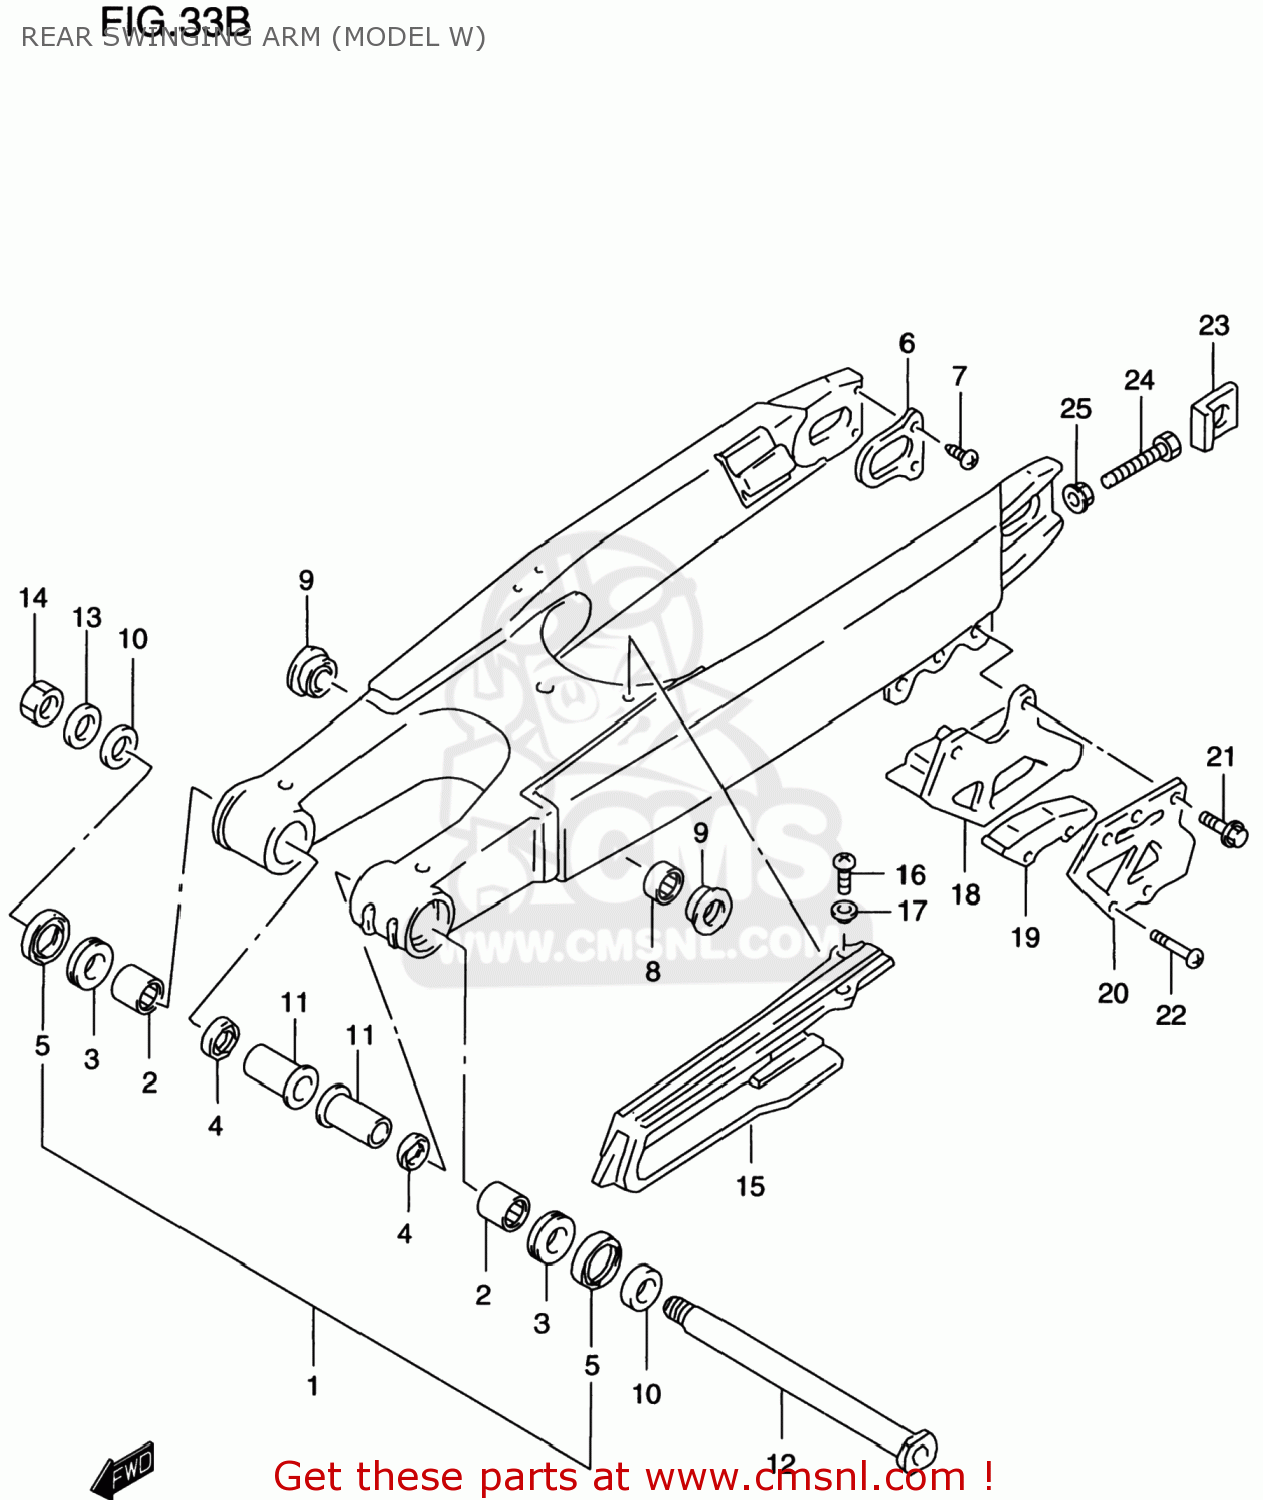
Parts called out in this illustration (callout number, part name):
1	SWING ARM ASSEMBLY,REAR
2	BEARING(22X29X30)
3	BEARING(22X35X2)
4	SEAL,OIL(22X29X4)
5	SEAL,RR SWGARM PIVOT OUTER
6	PLATE,SWING ARM RR
7	SCREW,UPPER
8	BEARING(22X28X16)
9	SEAL,SWINGING ARM RR
10	SPACER,RR SWGARM PIVOT OUTER
11	SPACER,SWGARM PIVOT INNER
12	SHAFT,RR SWINGINGARM PIVOT
13	WASHER, FIXED DRIVE FACE
14	NUT
15	BUFFER,CHAIN TOUCH DEFENSE
16	SCREW
17	WASHER
18	GUIDE,CHAIN
19	DEFENSE,CHAIN GUIDE
20	PLATE,CHAIN GUIDE OUTER
21	SCREW
22	SCREW(6X40)
23	WASHER,CHAIN ADJUSTER
24	BOLT(8X50)
25	NUT
